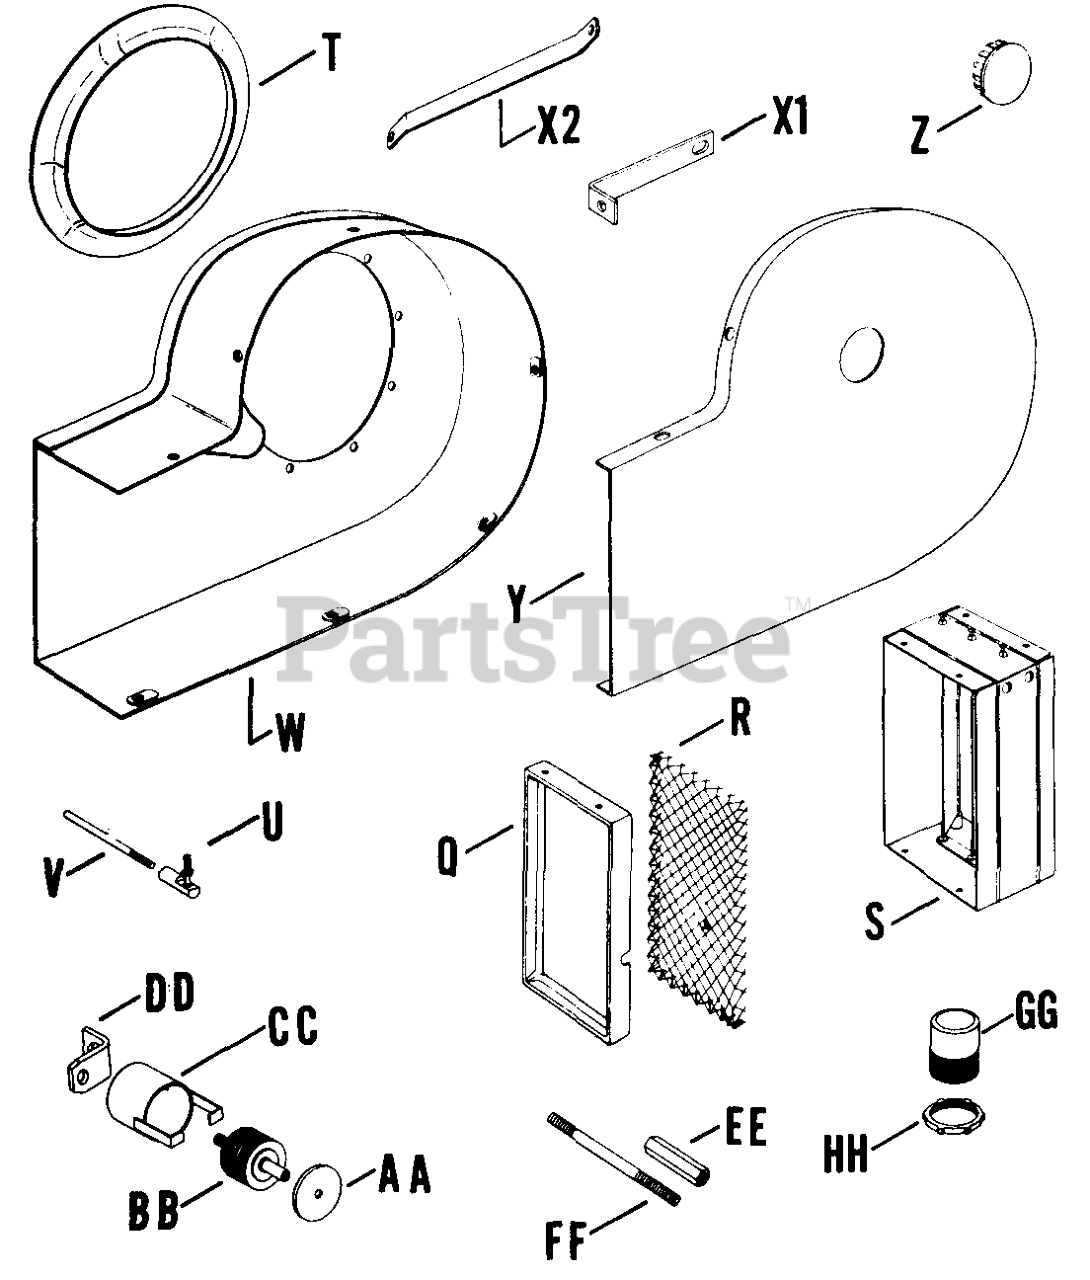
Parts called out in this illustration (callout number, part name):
R	SCREEN - DISCONTINUED
T	BAFFLE - DISCONTINUED
CC	CUP - USE 271578
